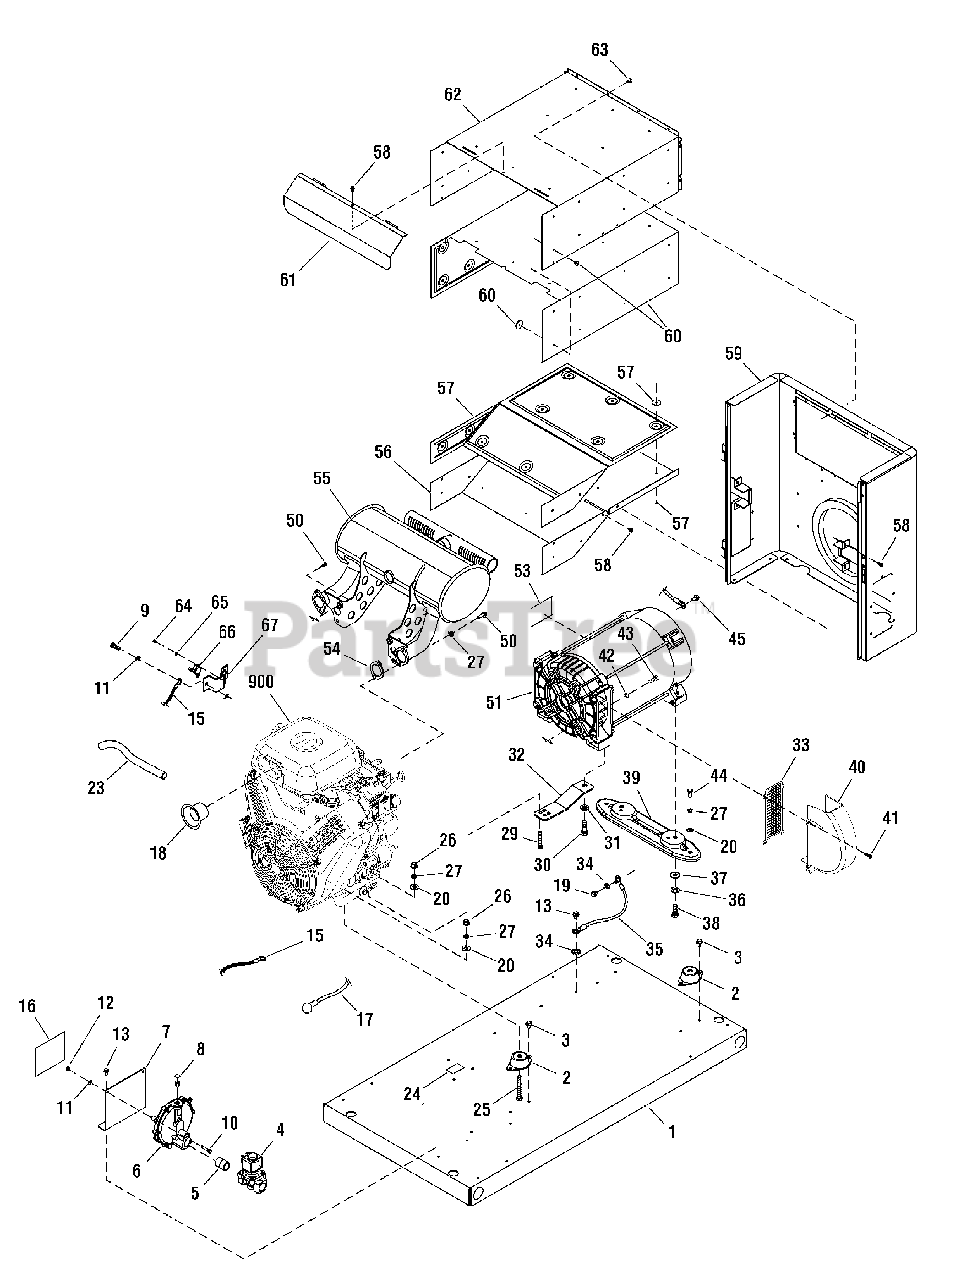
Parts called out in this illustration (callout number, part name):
2	MOUNT, Vibration
4	SOLENOID, Gas Fuel
6	REGULATOR, NG/LPG
9	* CAPSCREW, Hex Head, M6-1.0 x 16
10	* CAPSCREW, Hex Head, M6-1.0 x 30
11	* WASHER, Lock, 1/4
12	* NUT, M6-1.0
13	BOLT
15	CABLE, Battery, Black
17	CABLE, Battery, Red
19	* CAPSCREW, Hex Head, M6-1.0 x 12
20	* WASHER, Flat, 5/16-M8
23	HOSE, Oil Drain
24	DECAL
25	* CAPSCREW, Hex Head, 5/16-18 x 2-1/2
26	* NUT, 5/16-18
27	* WASHER, Lock, 5/16-M8
29	* CAPSCREW, Hex Head, 5/16-18 x 2
30	* CAPSCREW, Hex Head, M12-1.75 x 35
31	* WASHER, M12
32	SUPPORT, Engine
34	* WASHER, Shakeproof, M6 1/4
36	* WASHER, Lock, 3/8
37	* WASHER, Flat, 3/8
38	* CAPSCREW, Hex Head, 3/8-16 x 1
39	SUPPORT, Alternator
41	TAPTITE, M5.8 x 10
42	* WASHER, Lock, 3/8
43	* CAPSCREW, Socket Head, 3/8 x 1-1/4
44	* CAPSCREW, Hex Head, 5/16-18 x 3/4
45	BOLT
50	SCREW
51	ALTERNATOR
53	DECAL
59	BULKHEAD, Alternator
62	BOX, Muffler Top
64	* SCREW, Phillips Head, 4-40 x 0.19
65	* WASHER, Lock, #4
67	PLATE, Temp Switch
900	** ENGINE
